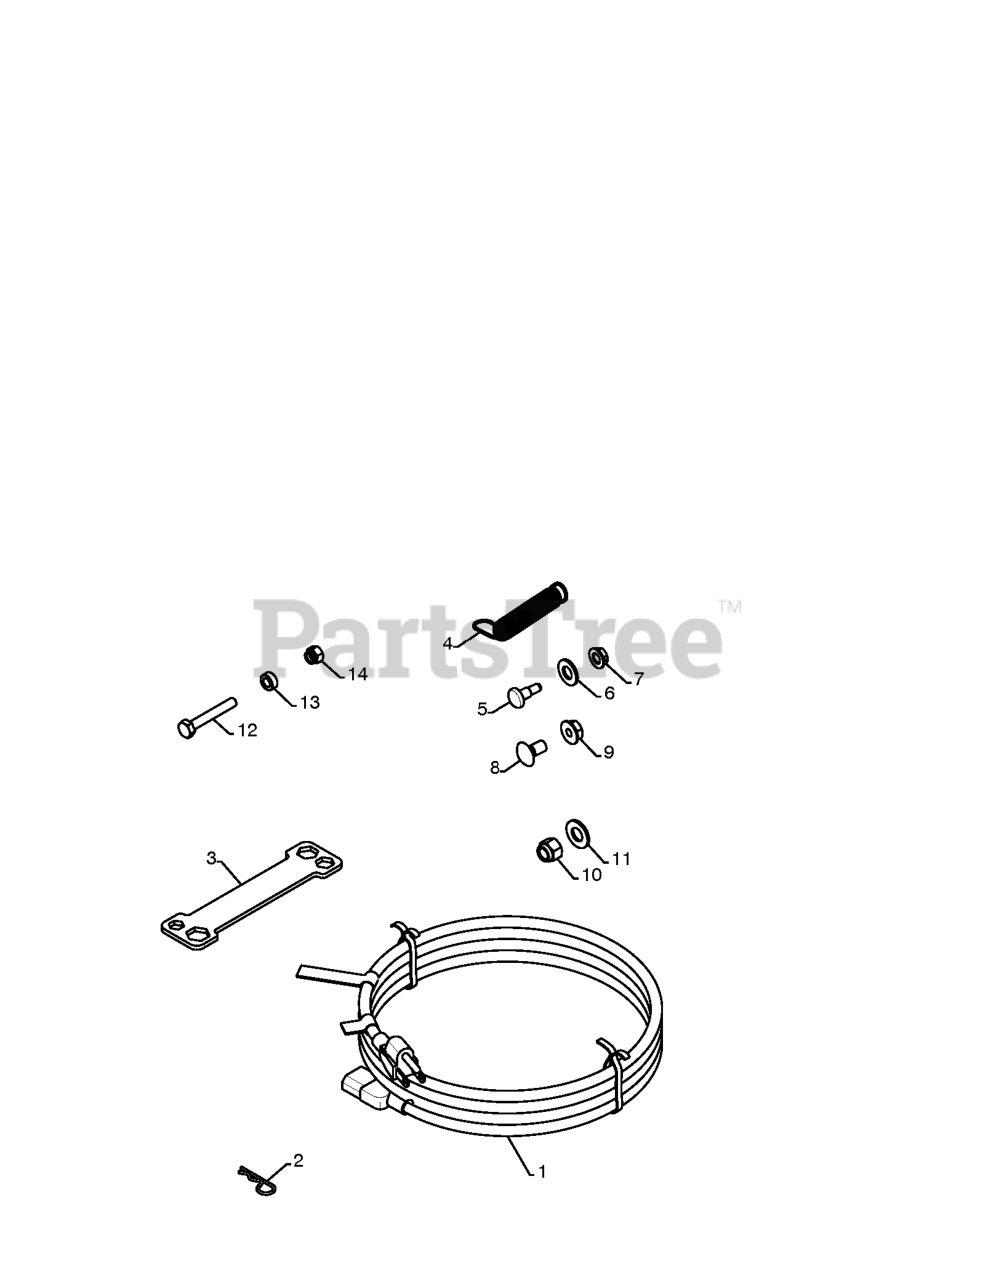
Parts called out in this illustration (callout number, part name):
1	CORD.ELECTRIC.10FT.120V.SNOW
2	SPRING RETAINER
3	RP WRENCH, SNOWTHROWER
4	SPRING.DEFLECTOR.REM.CHUTE
5	BOLT, SHOULDER
6	WASHER, NYLON FRICTION
7	NUT.HEX.FLANGE.1/4
8	BOLT
9	NUT.LOCK.5/16-18
10	NUT
11	WASHER
12	BOLT, SHEAR
13	SPACER.3943.SLEEVE.250X.47
14	LOCKNUT.NYLOC.1/4-20
